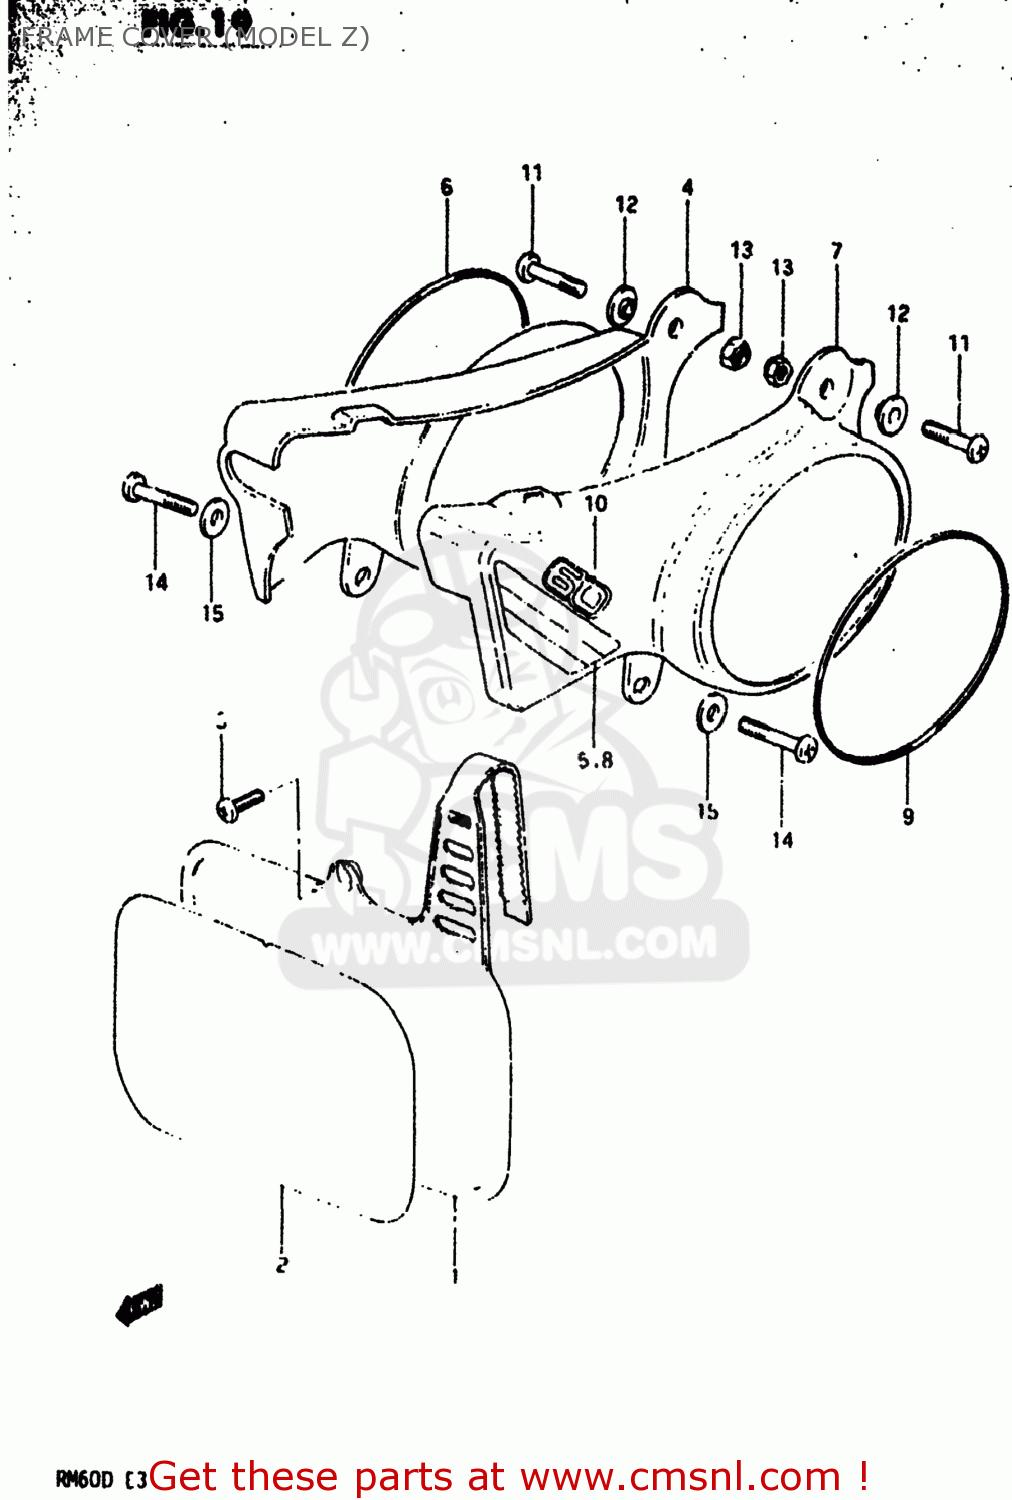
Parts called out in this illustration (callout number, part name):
1	PLATE,NUMBER,FRONT
2	EMBLEM,FRONT NUMBER PLATE
3	SCREW
4	COVER,FRAME,RIGHT
5	TAPE,FRAME COVER
6	TAPE,FRAME COVER NUMBER PLATE
7	COVER,FRAME,LEFT
8	TAPE,FRAME COVER
9	LABEL,FRAME COVER
10	EMBLEM
11	SCREW
12	WASHER
13	NUT
14	SCREW
15	WASHER
